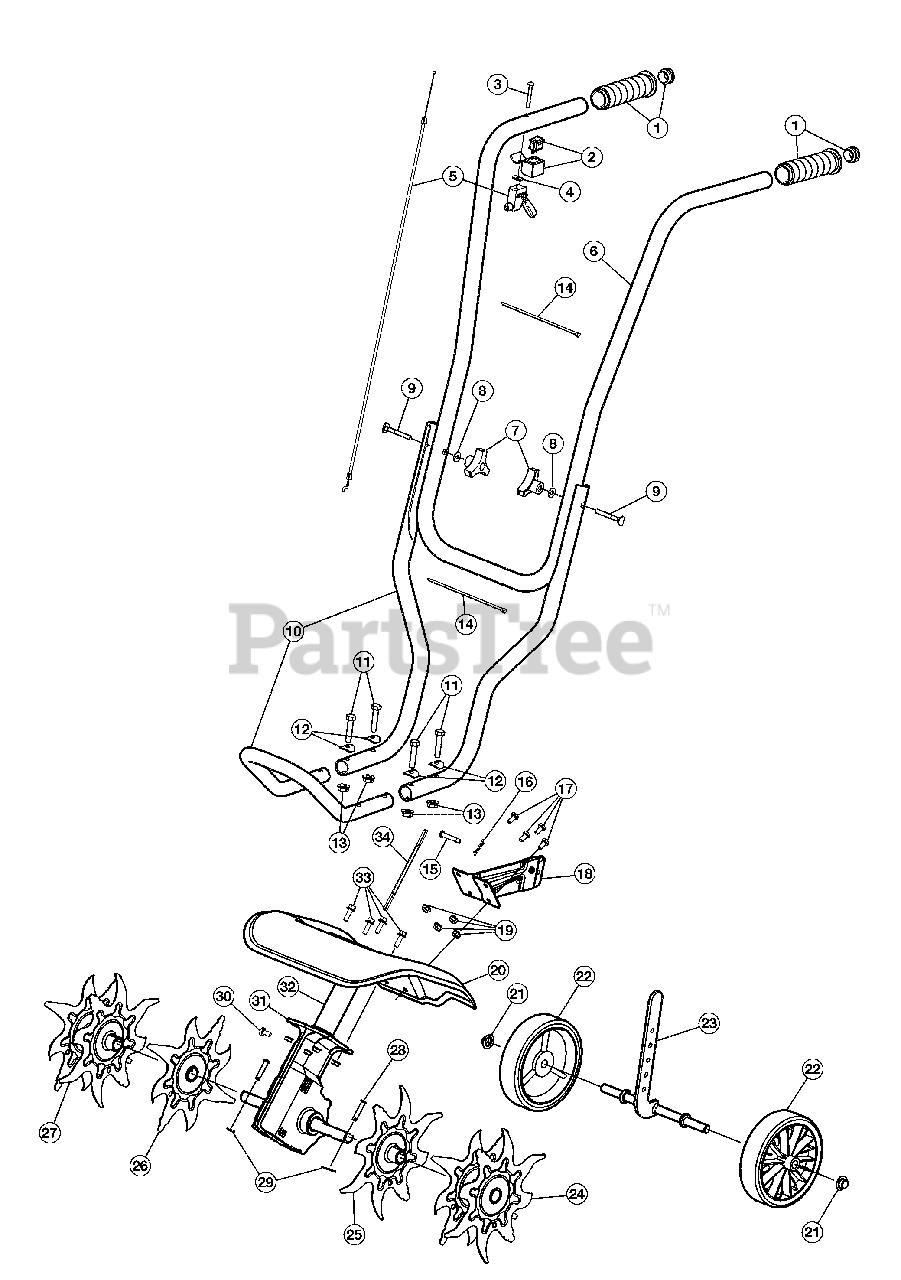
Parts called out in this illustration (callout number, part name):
2	Screw
3	Switch Assembly
5	Throttle Assembly
6	Upper Handle
8	Washer
9	Bolt
10	Lower Handle Assembly
11	Bolt
12	Washer
14	Cable Tie
15	Clevis Pin
16	Cotter Pin
17	Cap Screw
18	Tailpiece Bracket Assembly
20	Tine Shield
22	Wheel
23	Wheel Support Bracket Assembly
24	Tine (Left Outer)
25	Tine (Left Inner)
26	Tine (Right Inner)
27	Tine (Right Outer)
28	Clevis Pin
30	Sleeve Retaining Bolt
31	Gear Box Assembly
32	Drive Shaft Housing
34	Flex Shaft
